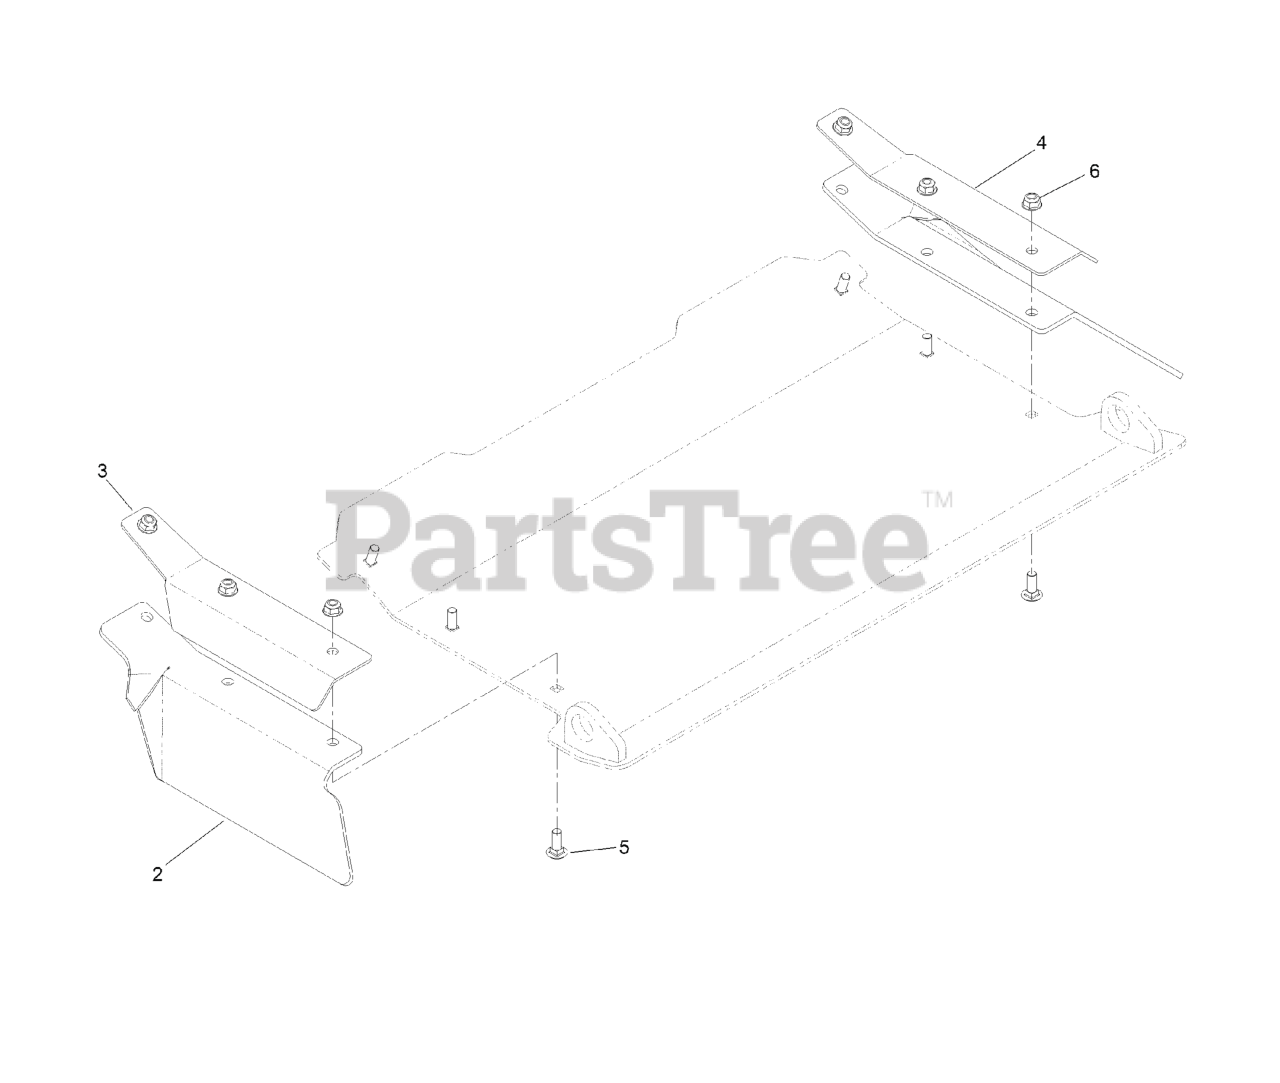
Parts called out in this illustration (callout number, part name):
2	FLAP-RUBBER
3	BRACKET-FLAP, LH
4	BRACKET-FLAP, RH
5	SCREW-CARR
6	NUT-HF, NI
